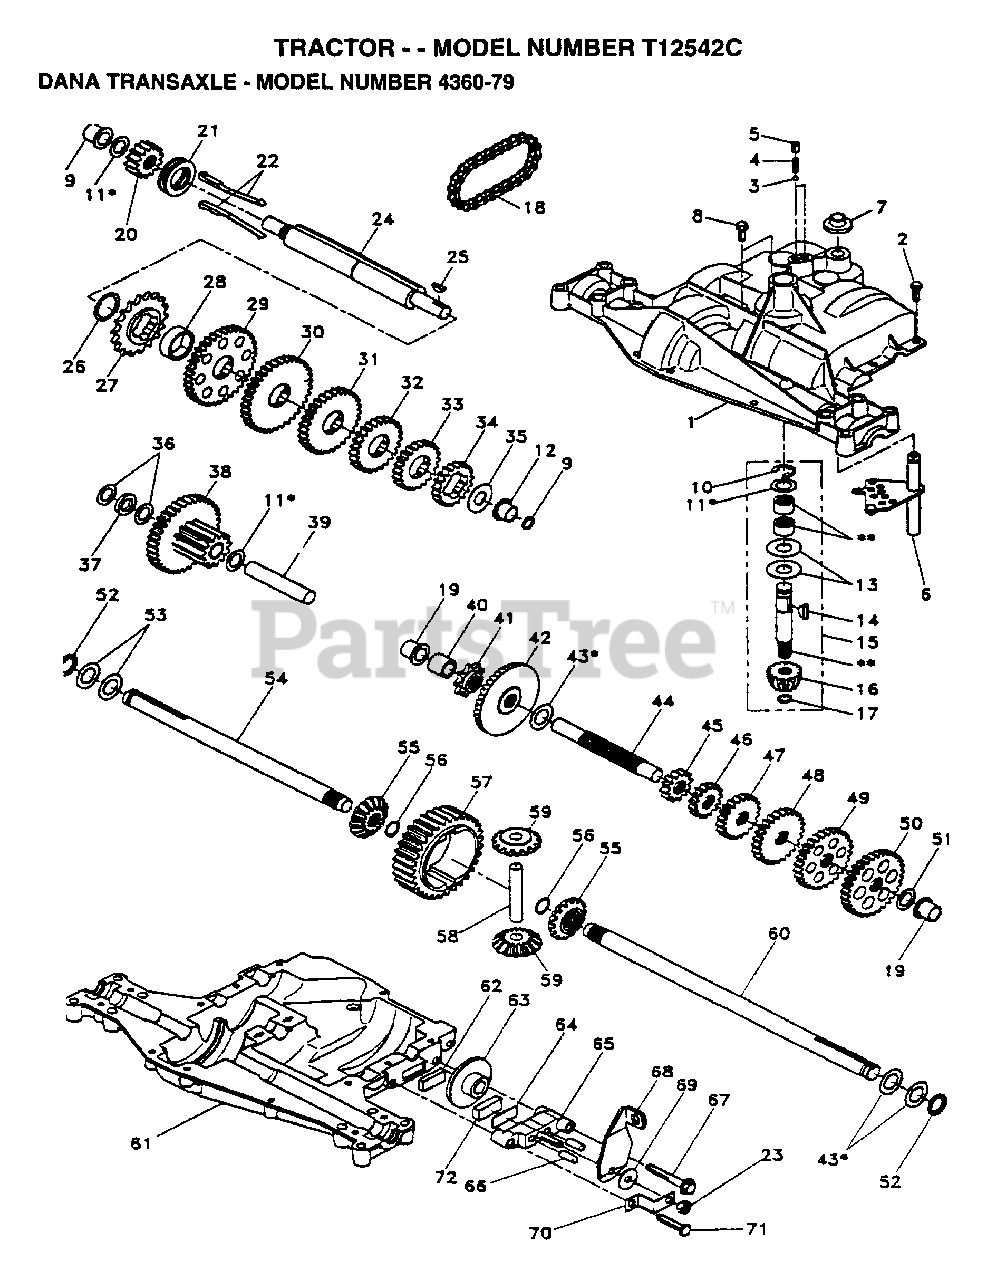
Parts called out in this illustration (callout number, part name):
1	HOUSING UPPER TRN
4	"SPRING, DETENT LT"
5	"SCREW, SET LT"
6	KIT SHIFTER ASM
7	SHIFTER BOOT
8	SCREW TAP W/SEAL
9	SQUARE RING
11	ASM KIT SHIM 4689
12	BEARING FLAN-DANA
13	WASHER T
14	KEY WOODRUFF-DANA
15	AS KIT INPUT SHFT
16	PINION 14T T
17	"RING,RETAINING LT"
18	"CHAIN,24 PTCH LT"
19	BEARING.FLNG.5510
20	GEAR SPUR 14 TTH
21	COLLAR CLUTCH
22	ASM KIT CLTCH KEY
23	NUT.LOCK.5/16-24
24	SHAFT INTERM DANA
25	WOODRUFF KEY
26	"RING,RETAINING LT"
27	SPROCKET 18T T
28	SPACER YT
29	GEAR SPUR 37 TTH
30	GEAR SPUR 35 TTH
32	GEAR 25T LT
33	GEAR SPUR 22 TT
34	SPUR GEAR 19T
35	"WASHER, PLAIN LT"
36	WASHER 025
37	SPACER
38	ASSM GEAR COMB
39	SHAFT IDLER
40	SPACER T
41	SPROCKET 9T LT
43	ASM KIT SHIM
44	SHAFT T
45	GEAR SPUR 12 TTH
46	GEAR SPUR 15 TTH
48	"GEAR, SPUR 25T LT"
49	GEAR 28T T
50	"GEAR, SPUR 31T LT"
51	WASHER 060
52	NEOPRENE WASHER
53	WASHER 031
55	GEAR 15T T
56	"RING,RETAINING LT"
58	SHAFT T
59	GEAR 1ST T
61	HOUSING LOWER TNS
62	PUCK T
63	BRAKE DISC. T
64	SPACER LT
66	PIN T
69	WASHER LT
71	"SCREW, TAPPING LT"
72	PUCK T
